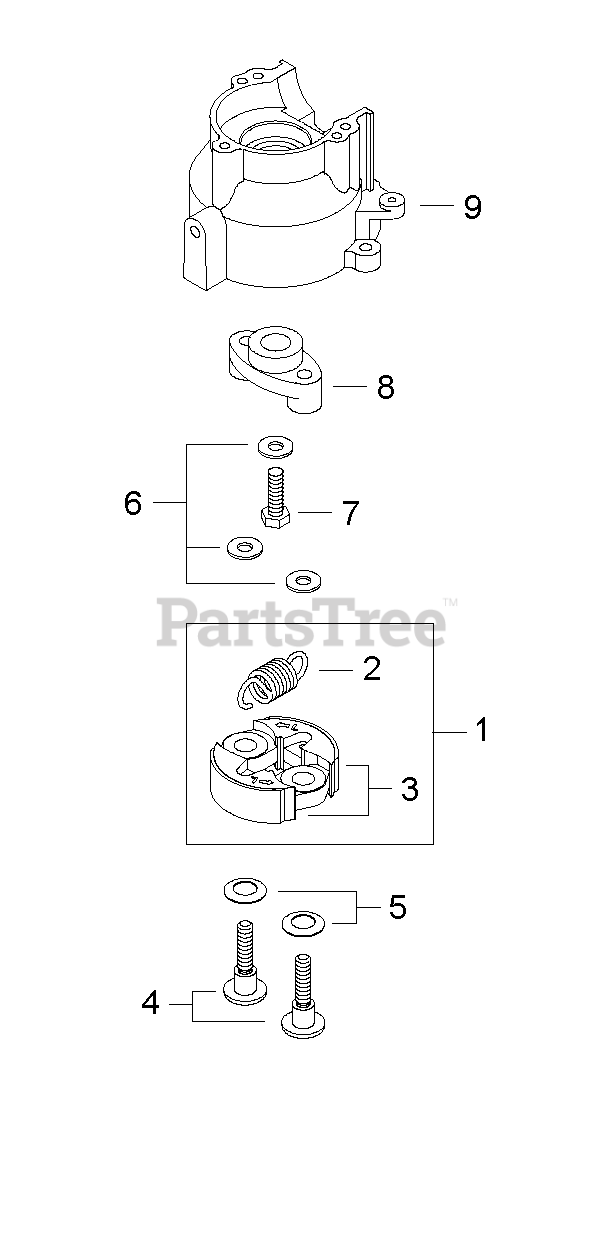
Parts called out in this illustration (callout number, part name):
1	CLUTCH ASSY
2	SPRING, CLUTCH
3	CLUTCH SHOE SET
4	BOLT, CLUTCH
5	WASHER - SPRING
6	WASHER - 6
7	SCREW - 6X18
8	HUB, CLUTCH
9	CRANKCASE ASSY
